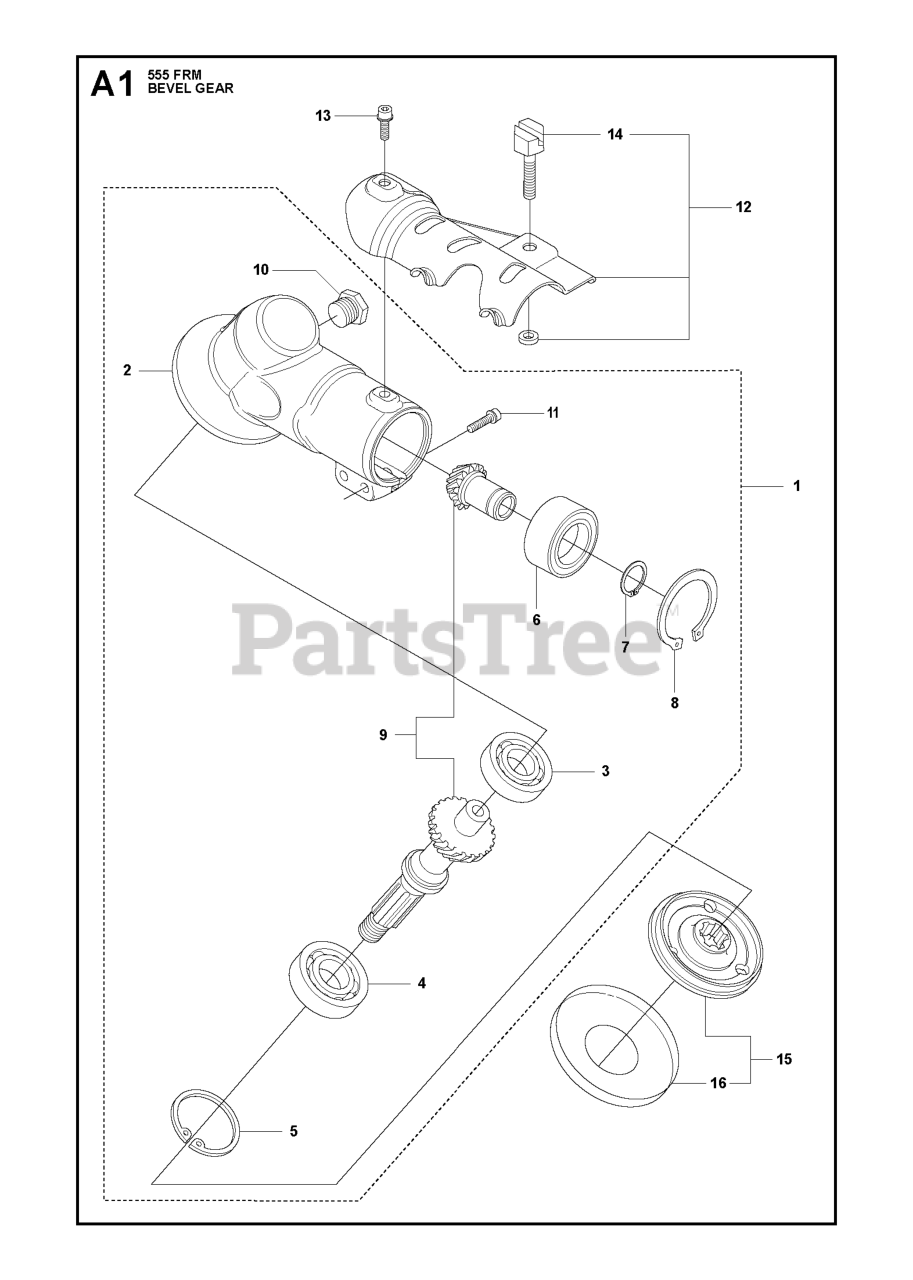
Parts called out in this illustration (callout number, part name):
2	GEAR HOUSING
3	BALL BEARING
4	BALL BEARING
5	RETAINING RING SGH 35
7	RETAINING RING SGA 15
8	RETAINING RING
9	BEVEL GEAR
13	BOLT W/WASHER
15	CARRIER
16	GRASS SEALING
